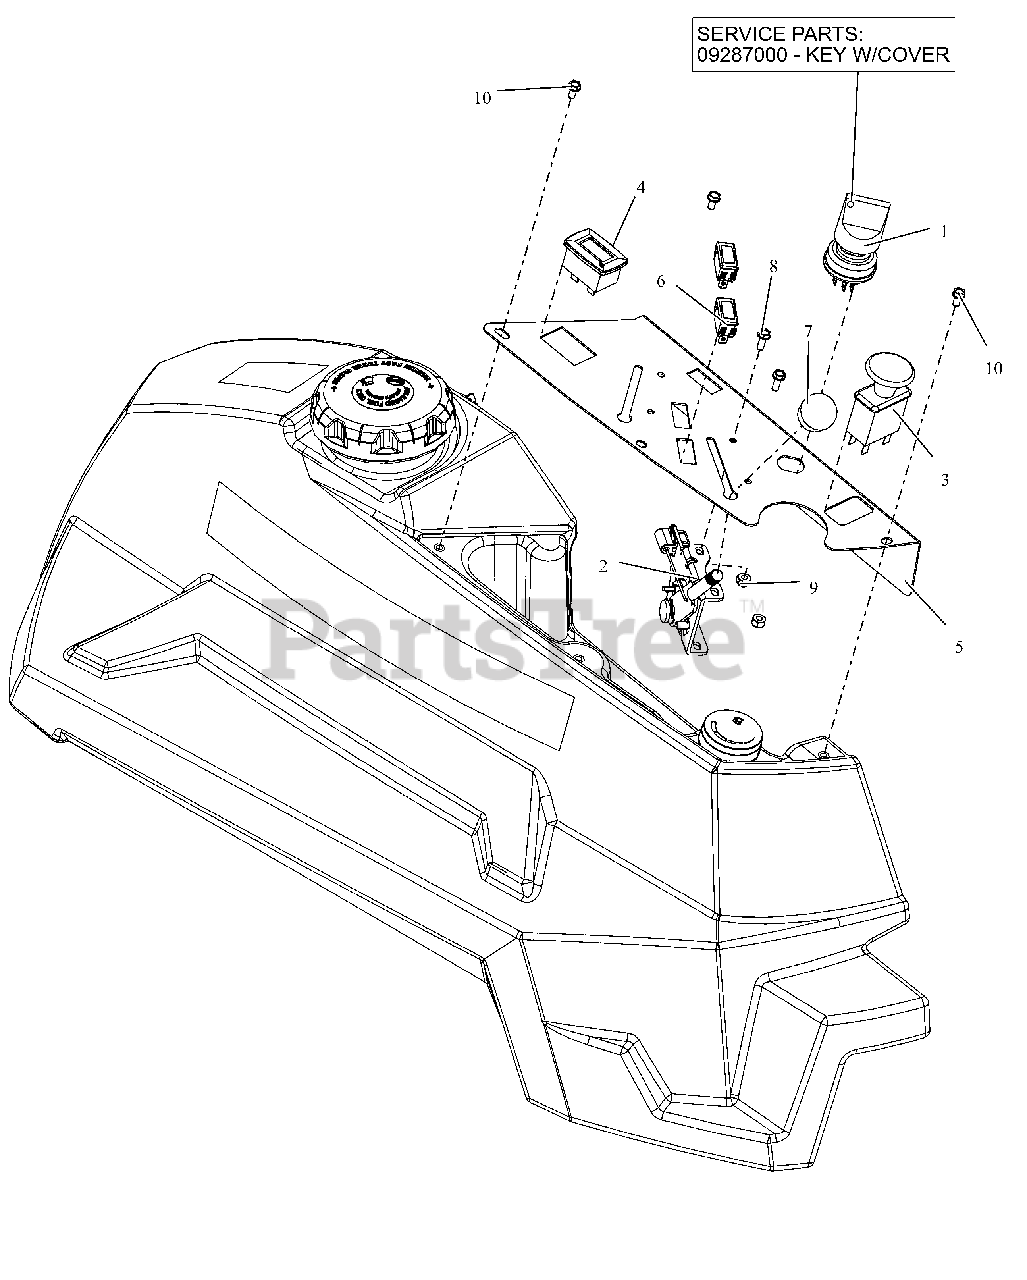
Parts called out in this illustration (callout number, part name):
1	SWITCH, IGNITION
1	KEY, W/ SHIELD
2	CABLE, PRO-CTRL 35.50"
3	SWITCH, CLUTCH
4	METER, HOUR W/MAINTENANCE
5	PT400 CONTROL PANEL - RED
6	LIGHT, INDICATOR (RED)
7	KNOB-CONTROL-BLACK .38-16X.50
8	BLT, HWH #10-24X.50 ZCC
9	NUT-LK-NYL #10-24 G2 ZCC
10	SCR-MCH 10-24X.38 HWHSTAINLESS
